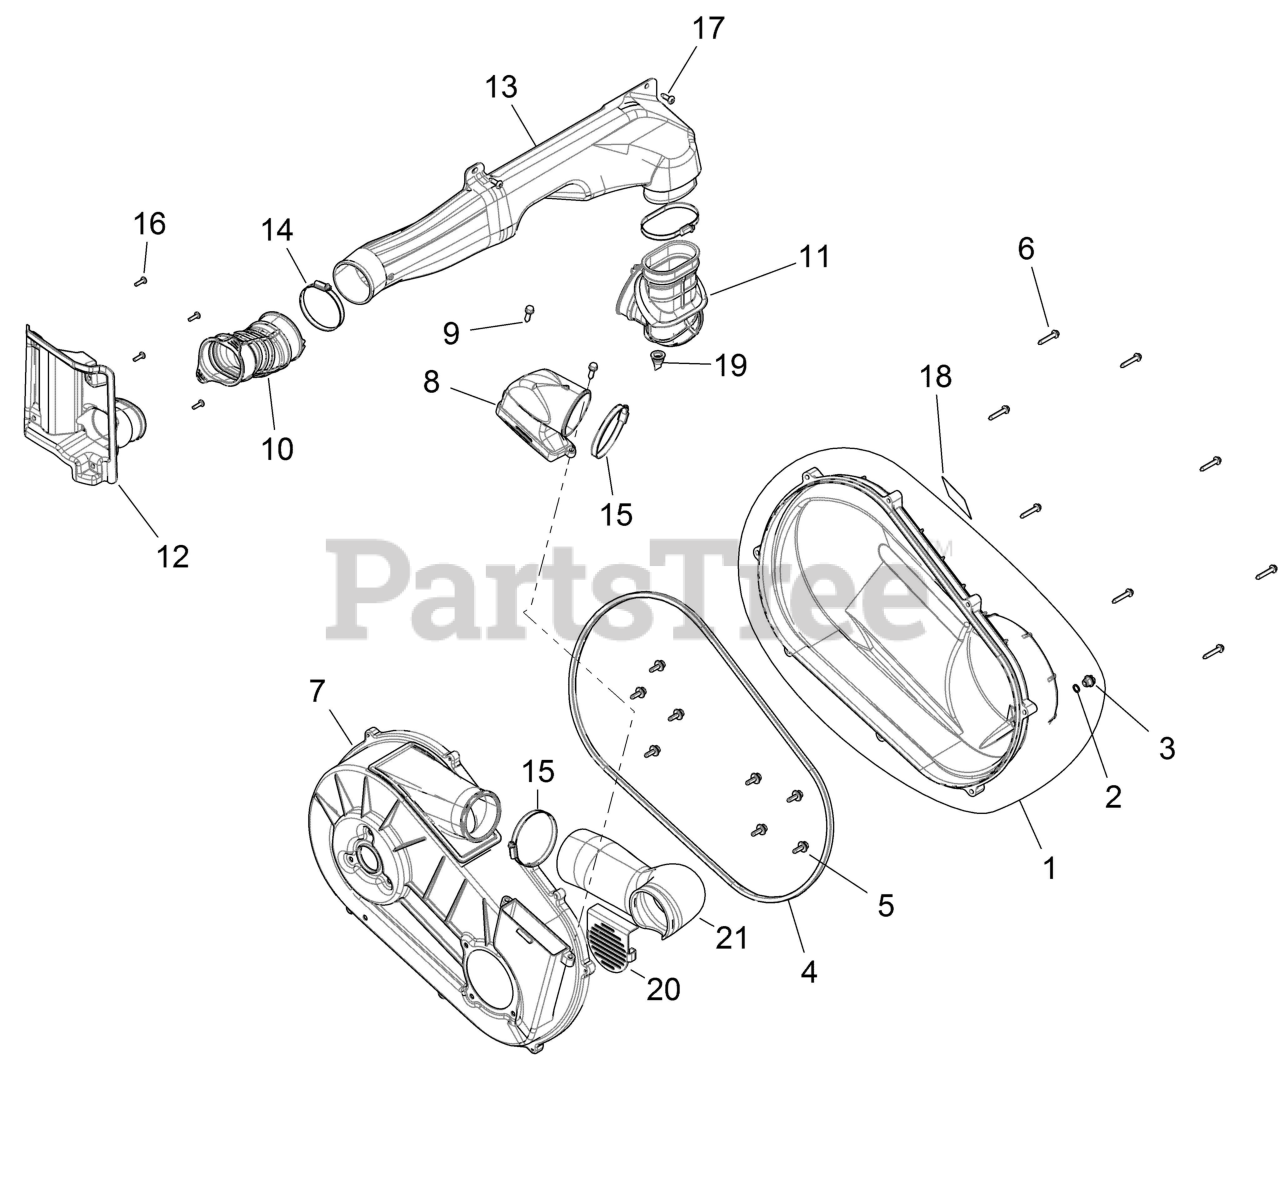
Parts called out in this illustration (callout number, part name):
1	ASM-COVER,CLUTCH,OUTER
2	O RING-.364X.504X.07
3	PLUG-DRAIN
4	SEAL-OUTER CLUTCH COVER
5	ASM-BOLT/WASHER,20 MM
6	SCR-HXFL-M6X35 ZOD HILO
7	ASM, INNER CLUTCH COVER
8	DUCT-CLUTCH,AIR IN
9	SCREW (10)
10	HOSE-INTAKE,CLUTCH
11	HOSE-CLUTCH,AIR IN,TRAP,570
12	INTAKE-FENDER-REAR
13	DUCT-INTAKE,CLUTCH
14	CLAMP,BAND,NARROW (10)
15	CLAMP-BAND,NARROW 70-90MM
16	SCR-10X5/8-HI/LO,PN-T25,TRX-M
17	SCR-TX TRUSS-#14X3/4,HI/LO ZBK
18	DECAL, BELT, CAUTION/CHECK
19	PLUG-DRAIN
20	BRKT, GRATE
21	HOSE, CLUTCH OUTLET
